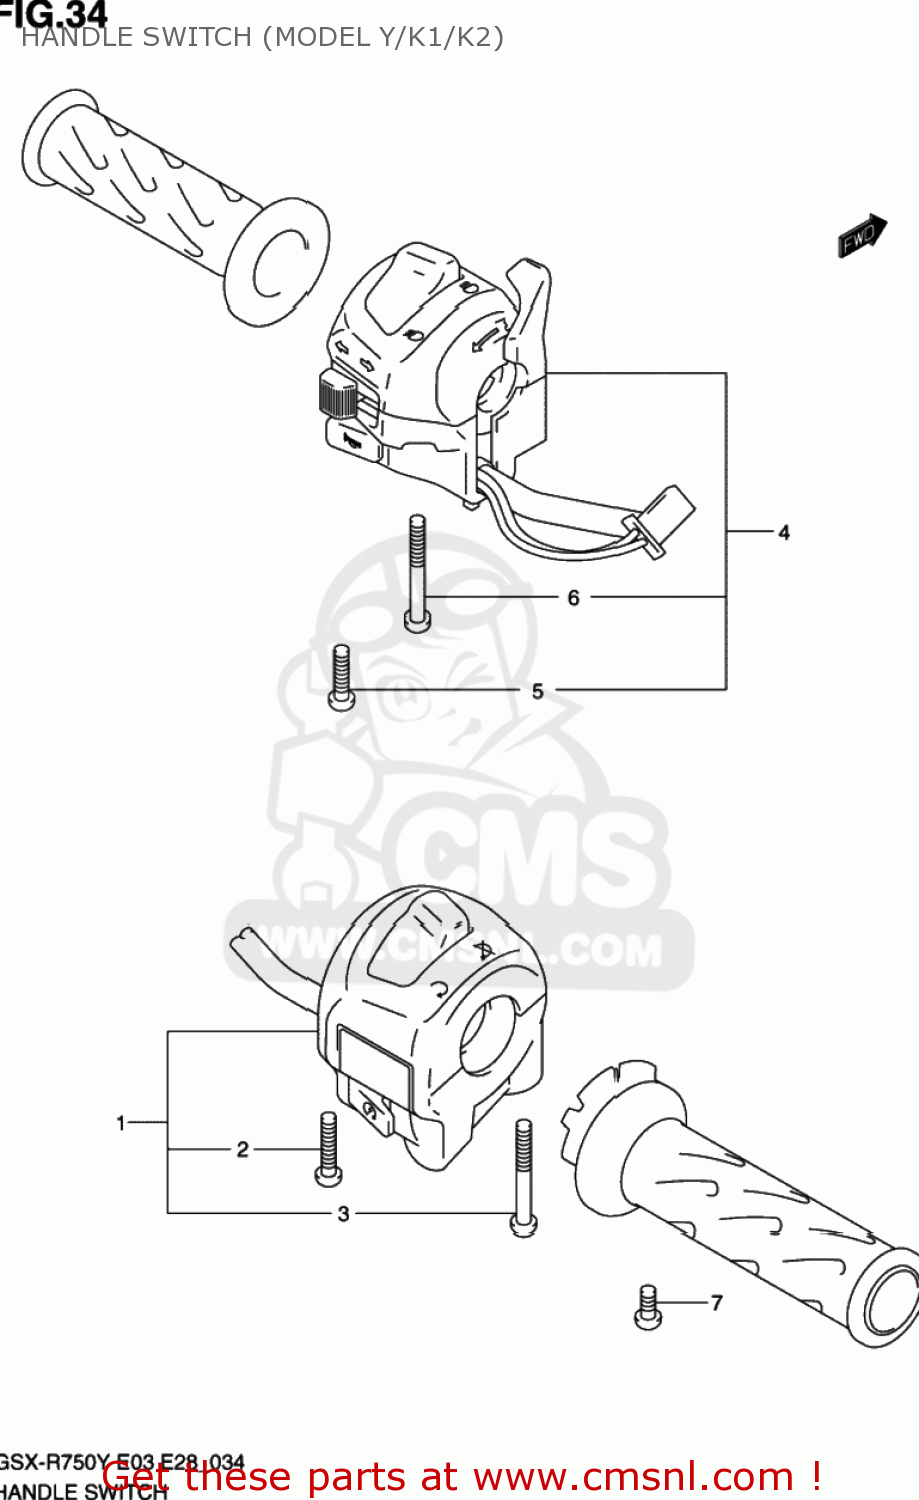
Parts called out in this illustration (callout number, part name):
1	SWITCH ASSY,HANDLE,R
2	SCREW
3	SCREW
4	SWITCH ASSY,HANDLE,L
5	SCREW
6	SCREW, 5X45
7	SCREW
